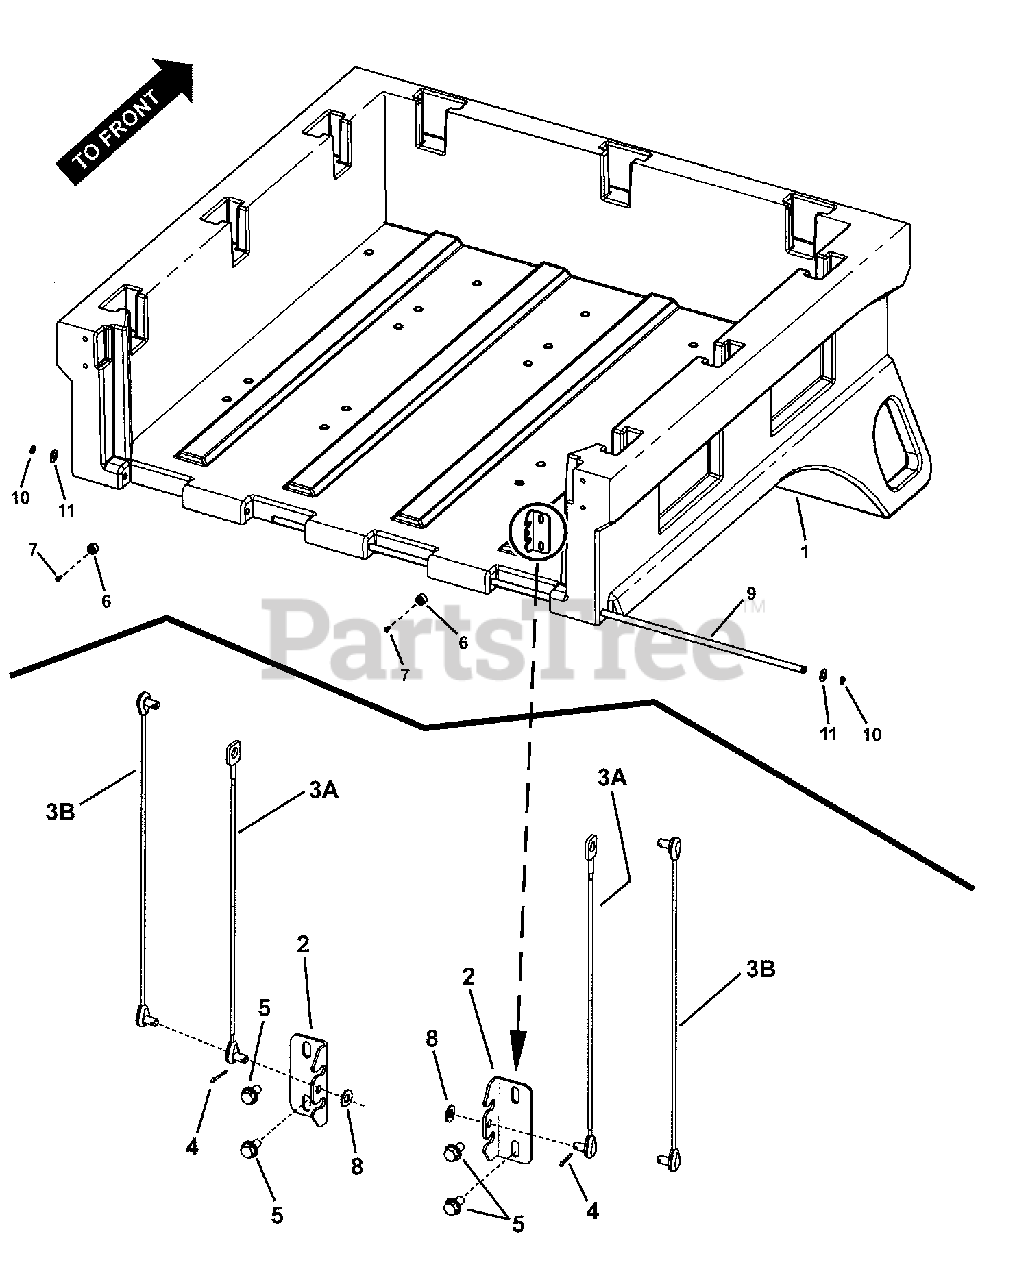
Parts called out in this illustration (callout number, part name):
1	BED, Plastic
2	BRACKET, Latch LH
3A	* LANYARD, Tailgate (1 pin & 1 hole end)
3B	LANYARD, Tailgate (2 pin ends)
4	COTTER PIN, 3/32 x 3/4"
5	BOLT, 5/16-18 x 5/8" Hex Flange Lock
6	BUMPER, Recess Style
7	SCREW, #10 x 5/8" HiLo Nail Point
8	WASHER, .34 x .69 x .08 Flat
9	ROD, Tailgate
10	RETAINING RING, 1/2", Heavy Duty
11	WASHER, .5 x 1.0 x .03 Flat
